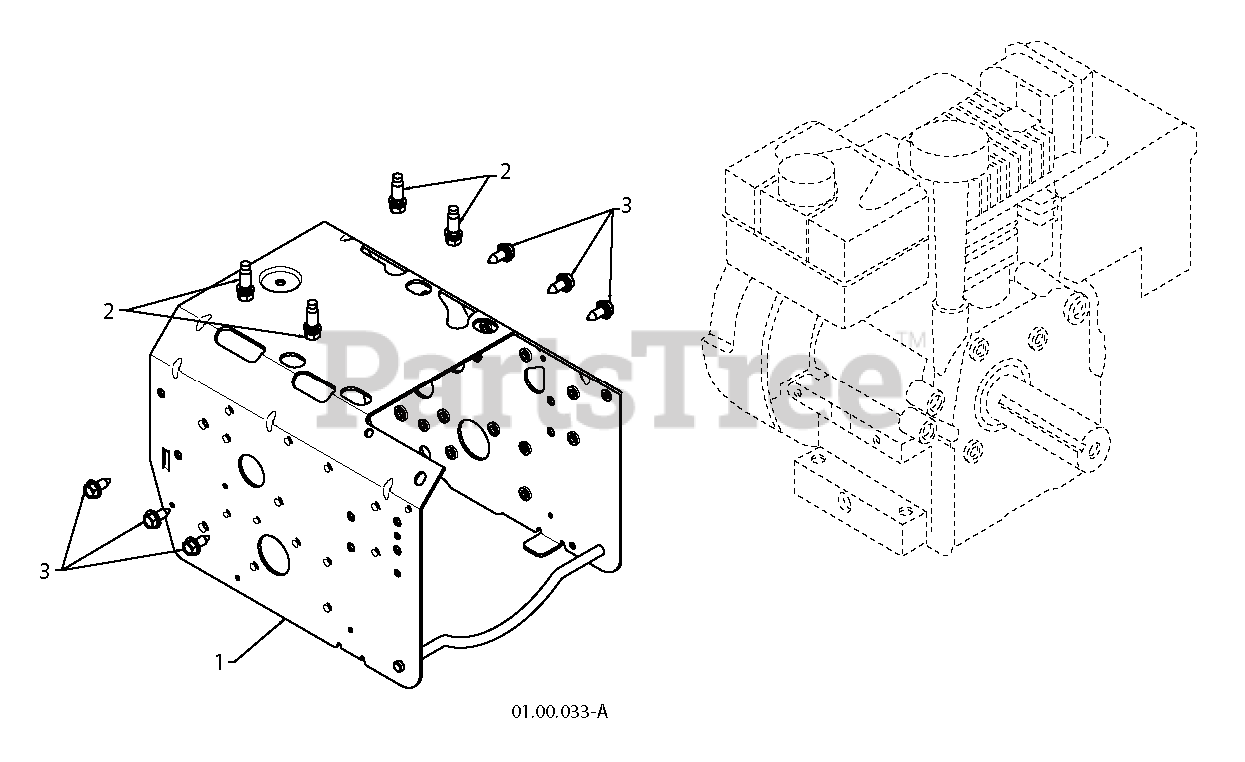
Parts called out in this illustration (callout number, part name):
1	FRAME.WELD.PNT.GEAR.ORANGE
2	BOLT 3/8-16X1-1/8
3	BOLT.HEX.HD.WASHER.5/16-18X.75
